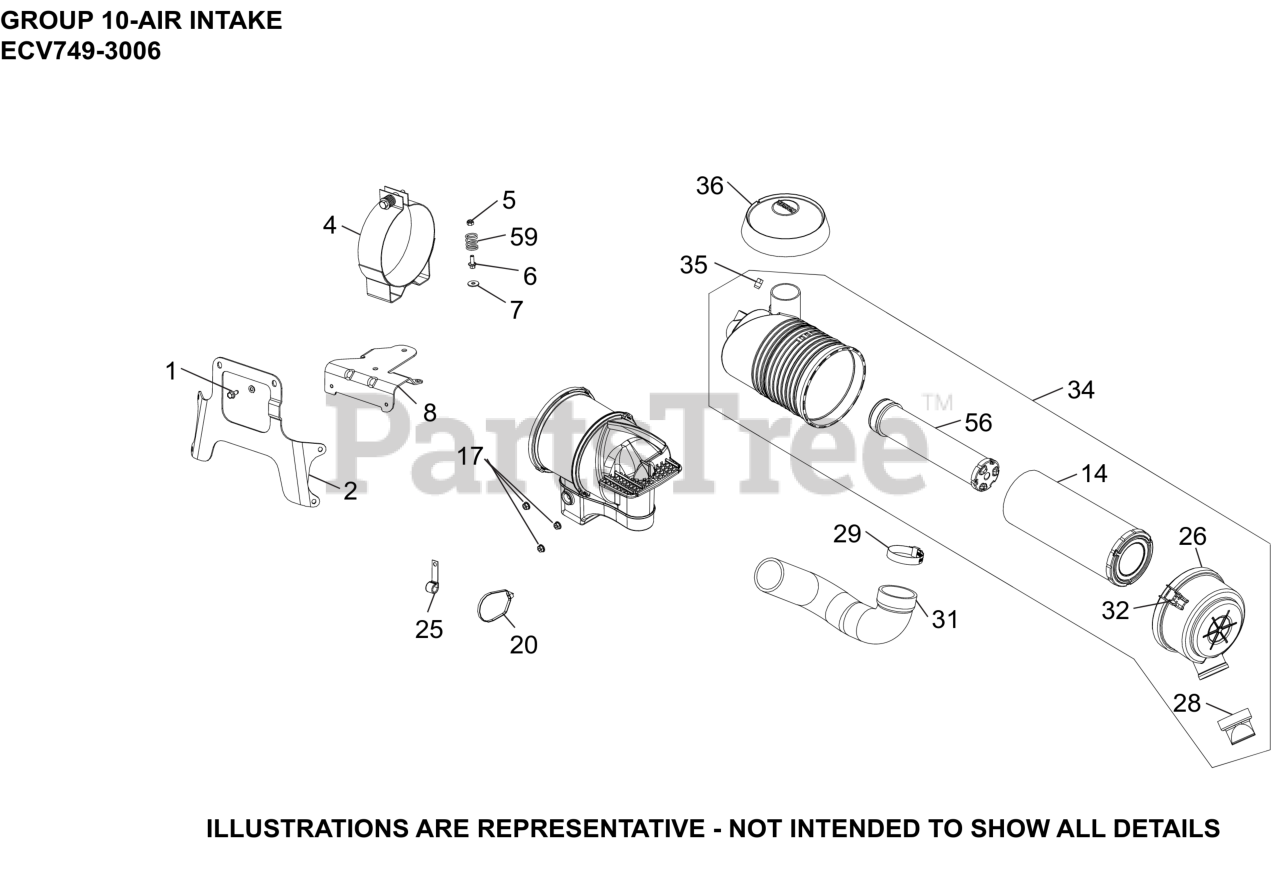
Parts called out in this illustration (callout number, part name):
1	SCREW, THREAD FORMING
2	BRACKET, MAIN SUPPORT
4	BRACKET, AIR CLEANER
5	NUT, LOCK M6X1.0
6	SCREW, FLG M6X1.0X16
7	WASHER, FLAT 1/4"
8	BRACKET, AIR CLEANER MOUNTING
14	ELEMENT, AIR FILTER - PRIMARY
17	NUT, FLG M6X1.0
25	CLIP, CABLE
26	COVER ASSEMBLY
28	VALVE, VACUATOR
29	CLAMP, HOSE-USE 25 237 21-S
29	CLAMP, HOSE
31	HOSE, AIR CLEANER
32	LATCH ASSEMBLY
34	AIR CLEANER ASSY
35	PLUG, PIPE
36	HOOD, INLET
56	ELEMENT, AIR FILTER - SAFETY
59	SPRING, AIR CLEANER BRACKET
